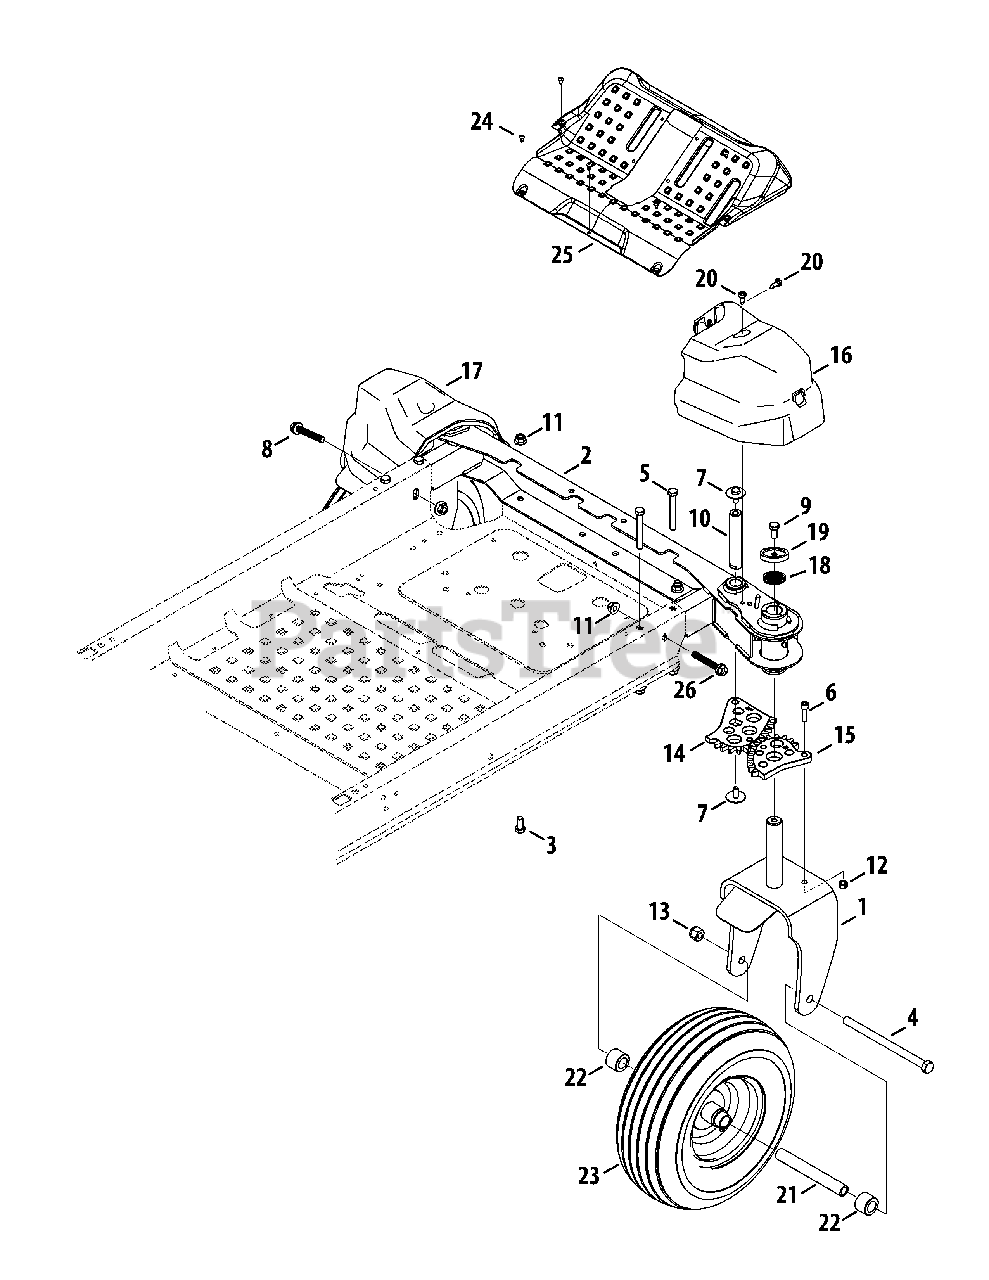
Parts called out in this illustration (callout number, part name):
1	Caster Wheel Bracket
2	Front Axle
3	Hex Cap Screw, 3/8-16 x .75
4	Bolt, 1/2-20 x 7.25
5	Screw, 3/8-16 x 2.75
6	Socket Head Screw, 5/16-18 x 1.00
7	Hex Cap Screw, 5/16-18 x .75
8	Hex Flange Screw, 3/8-16 x 2.25
9	Hex Screw, 3/8-16 x .75
10	Pivot Gear Steering Shaft
11	Flange Lock Nut, 3/8-16
12	Hex Lock Nut, 5/16-18
13	Hex Lock Nut, 1/2-20
14	12-Tooth Variable Gear
15	13-Tooth Variable Spur Gear
16	Axle Cover, RH
17	Axle Cover, LH
18	Wave Washer, 1.25 x 1.00 x .300
19	Shoulder Spacer, 1.75 x .180
20	Shoulder Screw, 1/4-20
21	Spacer, .51 ID x .75 OD x 5.825
22	Hub, .76 x 1.23 x .92 LG
23	Wheel Assembly, 13 x 5-6
24	Self Tapping Screw, 1/4-20 x .50
25	Floor Board
26	Hex Flange Screw, 3/8-16 x 2.00
